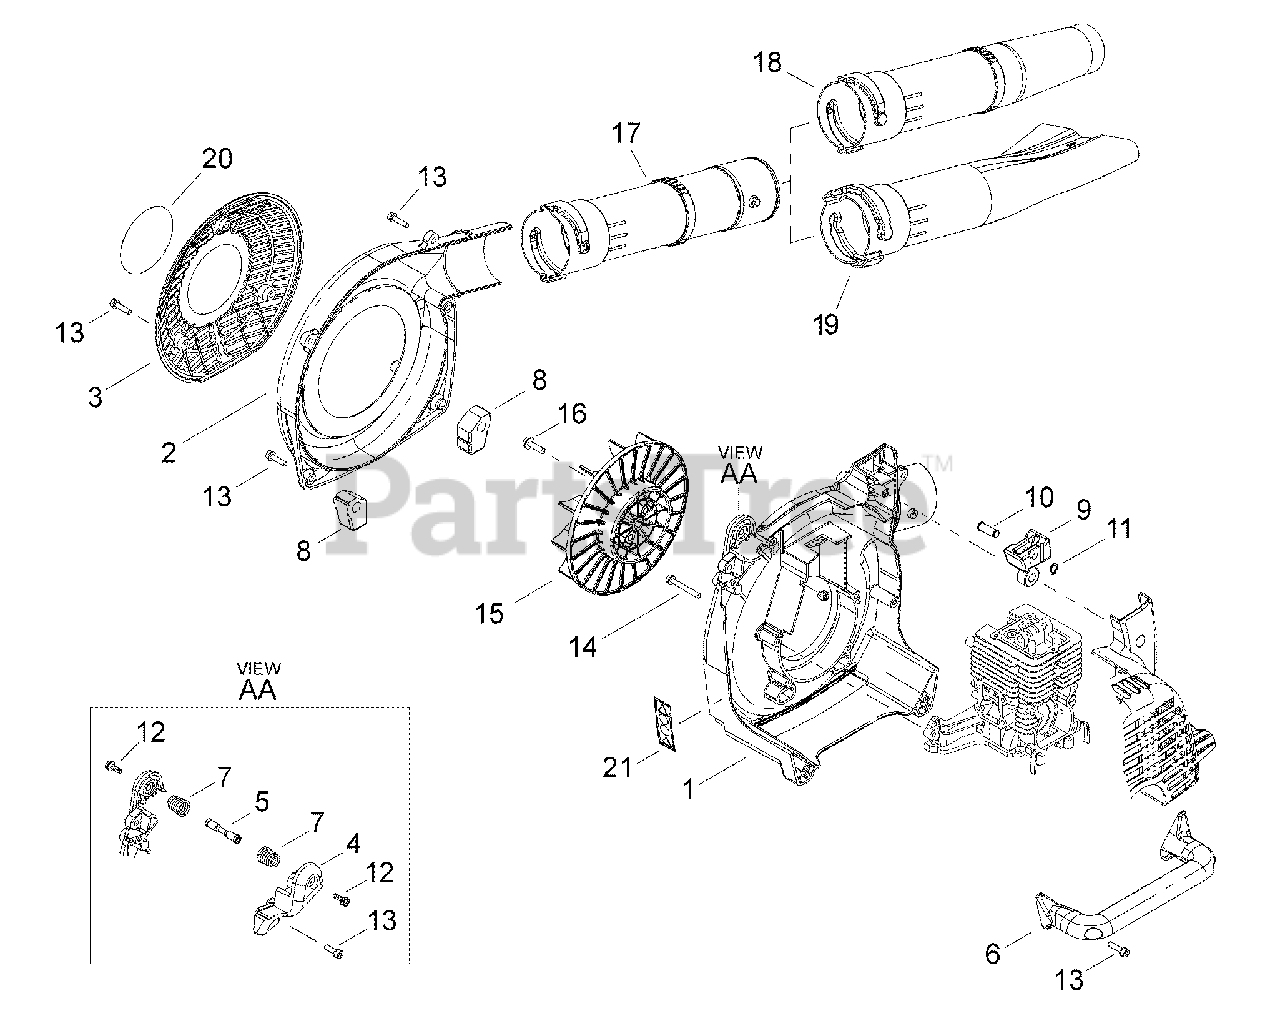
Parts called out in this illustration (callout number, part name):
1	COVER, FAN - RIGHT
2	COVER, FAN - LEFT
3	COVER, INTAKE
4	COVER, HANDLE
5	NUT
6	HANDLE - LOWER
7	SPRING
8	CUSHION - REAR
9	CUSHION - REAR
10	PIN - LOCKING
11	RING, RETAINING - 8
12	SCREW - 5X16
13	BOLT - 5X20
14	SCREW - 5X40
15	FAN
16	SCREW - 6X20
17	TUBE, BLOWER
18	NOZZLE
19	FAN TIP NOZZLE
20	LABEL - MODEL A4000
21	LABEL - CAUTION
